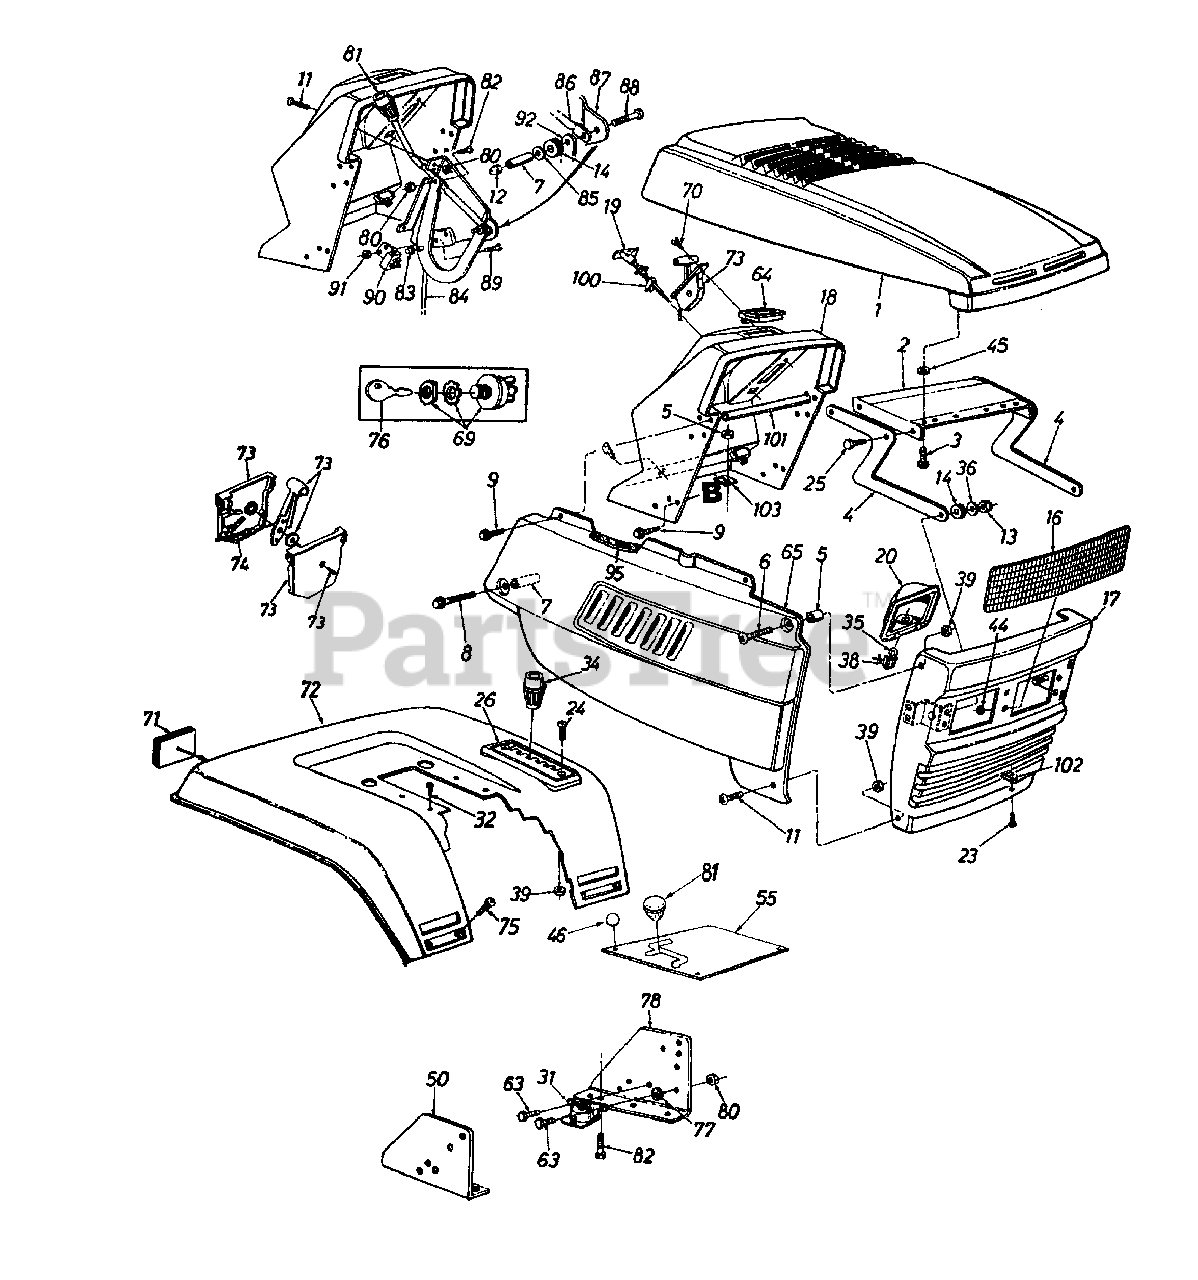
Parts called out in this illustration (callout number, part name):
1	Hood (Red)
6	Truss Hd. Mach. Scr. 1/4-20 Thd.
7	Spacer .26" I.D.
8	Hex Wash. TT-Tap Scr. 1/4-20 x 1.75" Lg
9	Hex TT-Tap, Scr. 1 /4-20 x .75"
11	Truss Mach. Scr. 1/4-20 x .5"
12	Hex Ins. L-Nut 1/4-20 Thd.
13	Hex L-Nut 5/16-18 Thd.
14	Rubber Washer
16	Headlight Lens
19	Choke Control
20	Headlight Housing
23	Hex Bolt 5/16-18 x .75"
24	Truss Mach. Scr. 1/4-20 x .75" Lg
25	Hex Wash. Hd. Scr. 1/4" x .5"
26	6-Speed Selector Plate
31	Solenoid
32	Hex Hd. Rolling Scr. 5/16-24 x .75"
34	Shift Knob
35	Lamp
36	Bell-Wash 34" I.D. x .87"
38	Socket
39	Hex Sems Nut 1/4-20 Thd.
44	Speed Nut 5/16" I.D.
45	Fl-Wash. .406" I.D.
46	Ball Knob
64	Ammeter
70	Truss Mach. AB-Tap Scr. #10 x .5"
71	Reflector
74	Throttle Control Wire 35"
75	Carriage Bolt 1/4-20 x .5"
76	Key
77	Ext. L-Wash. 1/4" I.D.
81	Knob
82	Hex Bolt 1/4-20 x .62"
83	Push Nut
84	PTO Rod
85	Fl-Wash. .281" I.D. x .73"
86	PTO Lever
89	Truss Mach. Scr. #10-24 x .5"
90	Safety Switch
91	Hex Nut #10-24 Thd.
92	PTO Bracket
95	Trim Strip 12"
100	Retainer Clip
101	Dash Support Tube
102	U-Nut 5/16-18 Thd.
103	Dash Panel Fastening Tab
